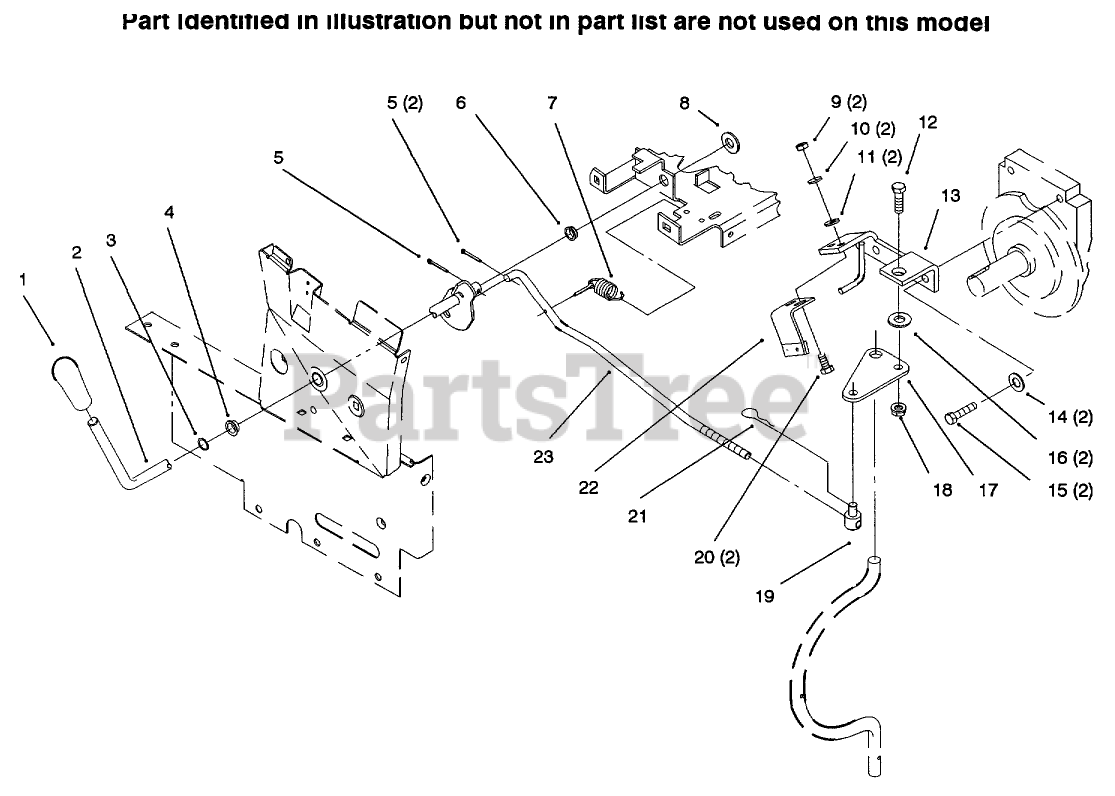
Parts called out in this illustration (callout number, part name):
2	PTO CLUTCH LEVER ASM
3	RING-EXT GRIP
4	BUSHING-NYLINER
5	PIN-COTTER
6	BUSHING-NYLINER
7	SPRING
8	SHIM-WASHER
9	NUT-JAM
10	WASHER-LOCK
11	WASHER-FLAT
12	SCREW-HH
14	WASHER-LOCK
15	SCREW-HH
16	SPACER-LIFT LINK
17	PLATE
18	NUT-LOCK, NI
21	PIN-HAIR
22	BRAKE ASM
23	ROD-PTO CLUTCH
